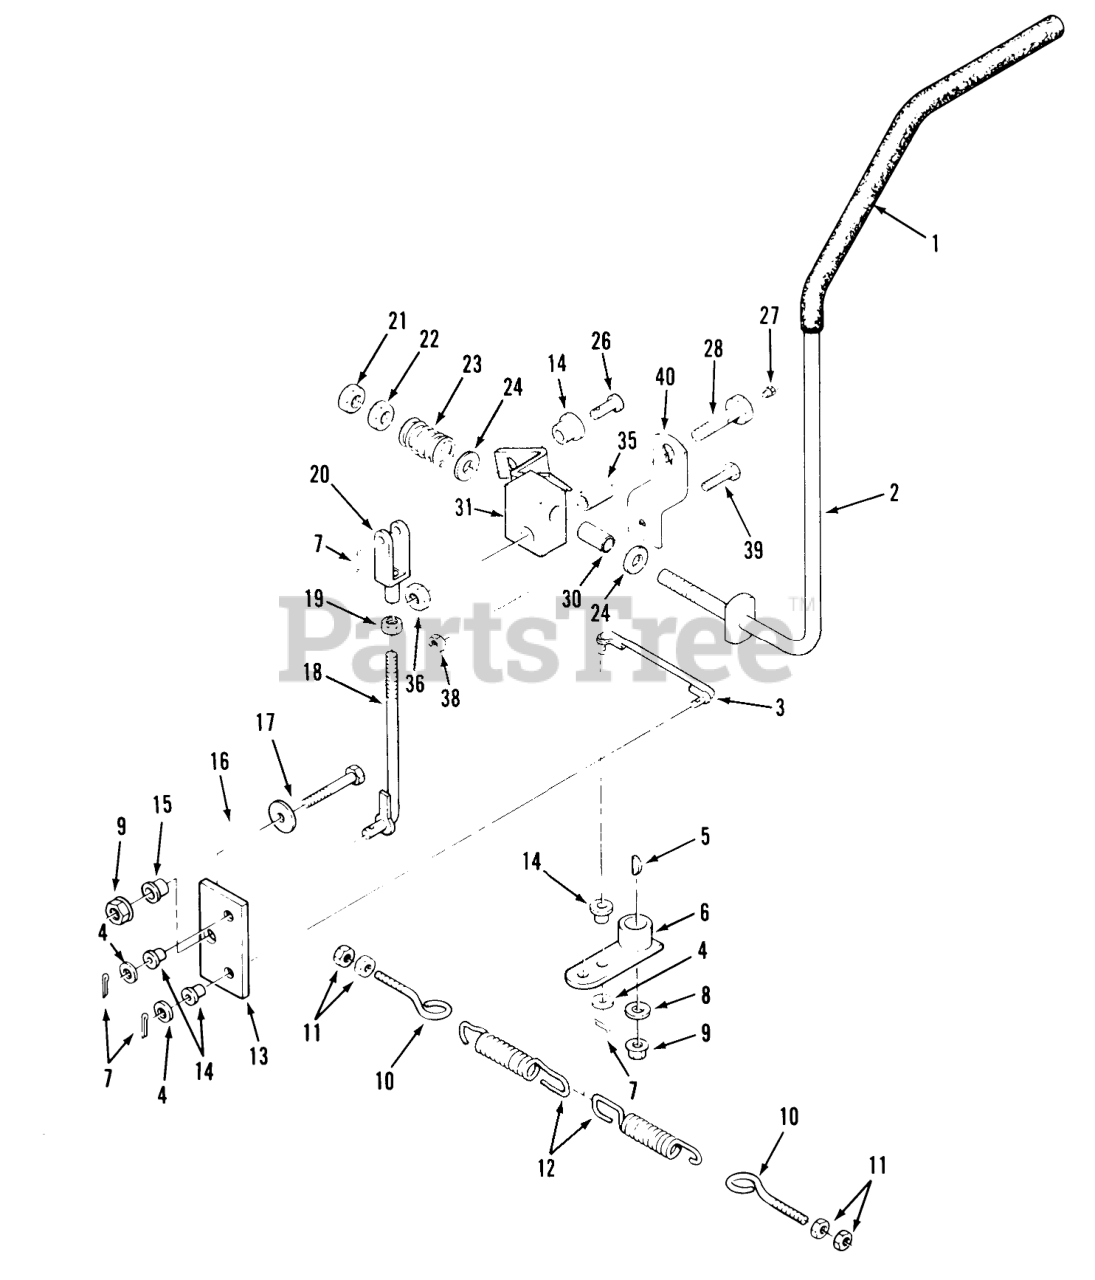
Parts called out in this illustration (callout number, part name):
1	Grip
2	WLDMT-STEER LVR LH B
3	ROD-STEERING R.H.
4	WASHER-PLAIN
5	KEY WOODR 1/8X1/2 DI
6	Arm-Hydro Control
7	PIN-COTTER
8	WASHER-FLAT
9	NUT-LOCK, NI
10	EYE BOLT 1/4-20
11	NUT-HEX
12	SPG-NEUTRAL 20217-35
13	PLATE-STEERING PI B
14	BUSHING-FLANGED
15	SPACER-LIFT LINK
16	WASHER
17	SCREW-HH
18	ASS'Y-ROD
19	NUT-HEX
20	YOKE
21	NUT-JAM
22	NUT-LOCK, NI
23	SPRING
24	WASHER-FLAT
26	PIN-YOKE
27	FITTING-GREASE
28	Bolt-Shoulder (Incl. Item #27)
30	BUSHING-STR LVR PVT
31	Steering Lever LH
35	BUSHING
36	NUT-LOCK, NI
38	NUT-LOCK, NI
39	SCREW-HH
40	STRAP-PIVOT B
